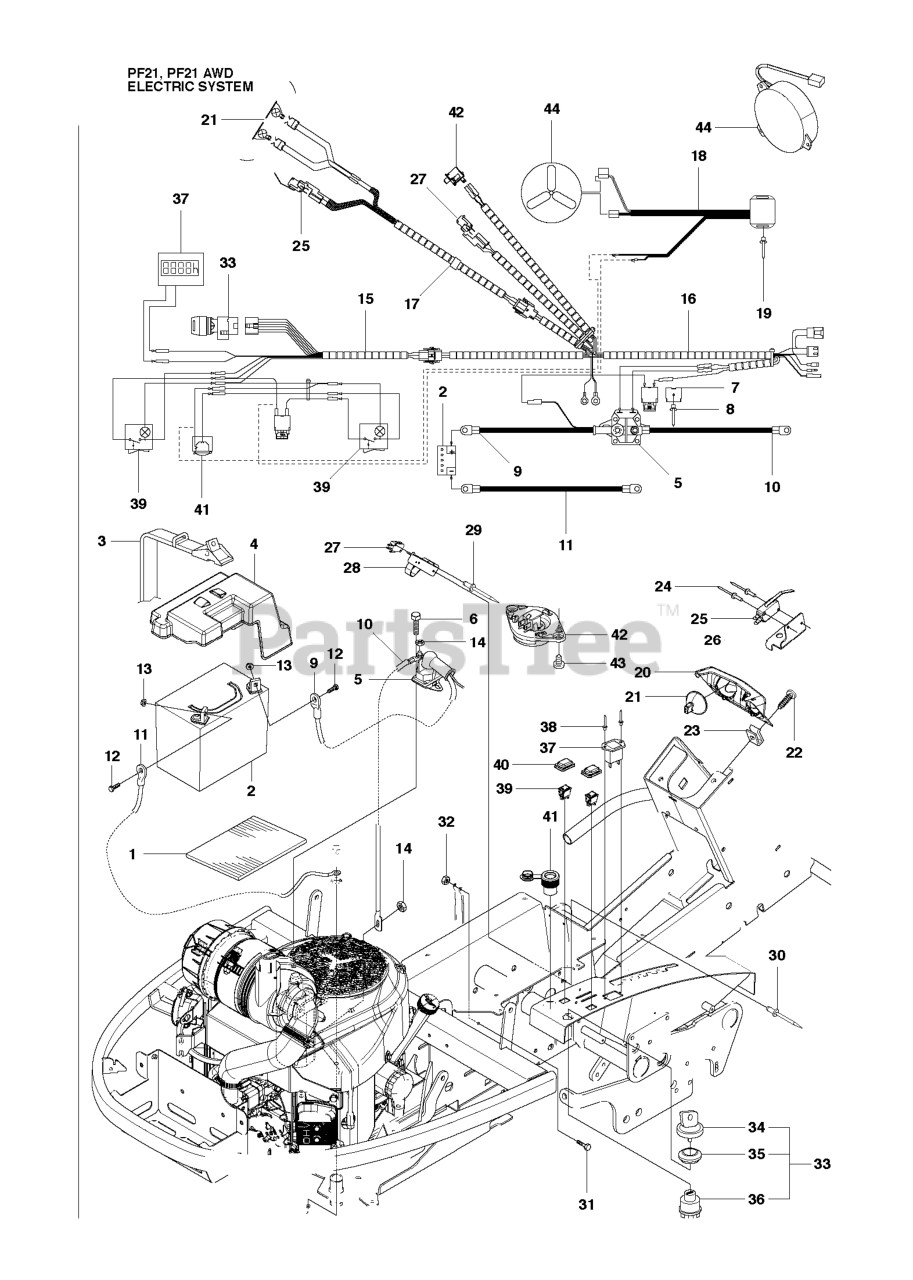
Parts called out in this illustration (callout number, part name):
9	CABLE
12	SCREW EHHM
15	WIRING CONTROL PANEL
25	RP MICRO SWITCH
27	%BRAKER
37	HOUR METER
42	ANTI-START SWITCH CPL
43	SCREW
